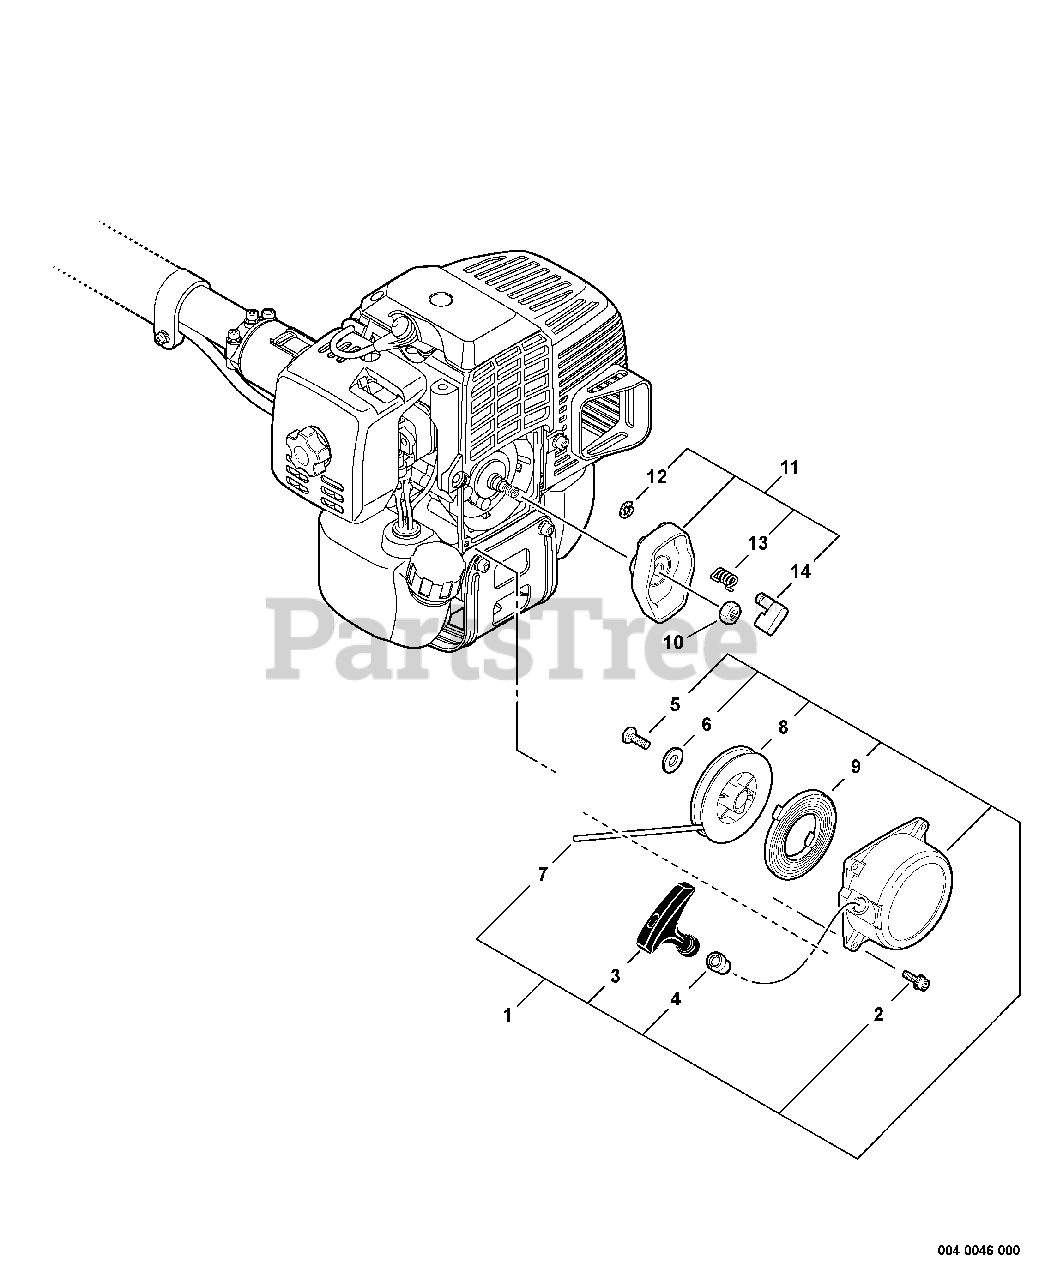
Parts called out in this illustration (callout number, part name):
1	STARTER ASSY
2	SCREW - 4X14
3	GRIP, STARTER
4	GUIDE, ROPE
7	ROPE, STARTER - 4X880
8	REEL, ROPE
9	SPRING, REWIND
11	STARTER PAWL ASSY
12	RING, RETAINING - 4
13	SPRING, RETURN
14	PAWL, STARTER
